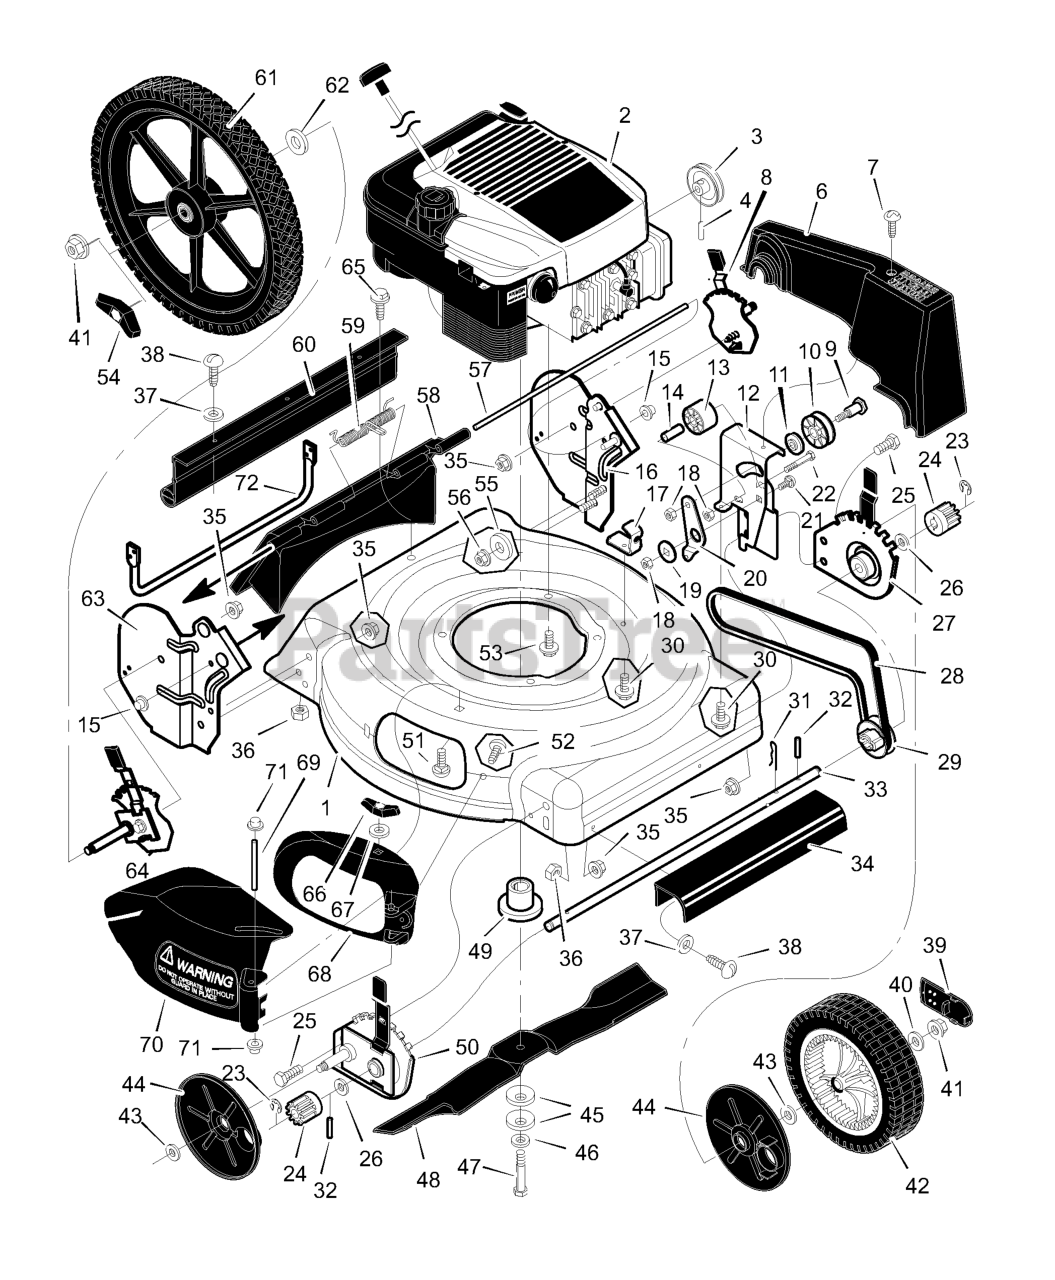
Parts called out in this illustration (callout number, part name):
1	Housing
2	Engine *
3	Pulley, Engine
4	Pin, Spring
6	Cover, Belt (Gray)
8	Adjuster, Left Rear Height
9	Bolt, Shoulder
12	Bracket, Idler Support
13	Pulley, Idler
14	Bearing
15	Nut, Push
16	Bracket, Left Handle
17	Bracket, Cable
18	Nut, Hex
20	Arm, Idler
21	Bolt, Carriage
22	Bolt, Shoulder
24	Gear, Pinion
25	Bolt
27	Adjuster, Left Frt Height
29	Pulley, Axle
31	Pin, Hair
32	Pin, Spring
34	Cover, Axle (Gray)
35	Nut, Flange
36	Nut, Hex
39	Hub Cap
40	Washer
41	Nut, Flange
42	Wheel, Drive
44	Cover, Dust
45	Washer, Belleville
49	Adapter, Blade
50	Adjuster, Right Frt Height
51	Bolt, Carriage
53	Bolt, Engine
55	Washer
56	Nut, Flange
57	Rod, Pivot
58	Door, Rear (Gray)
60	Deflector, Rear
61	Wheel, Rear
63	Bracket, Right Handle
64	Adjuster, Right Rear Hight
66	Wingnut
67	Retainer, Push
69	Pin, Pivot
70	Deflector, Chute
71	Push On Cap
